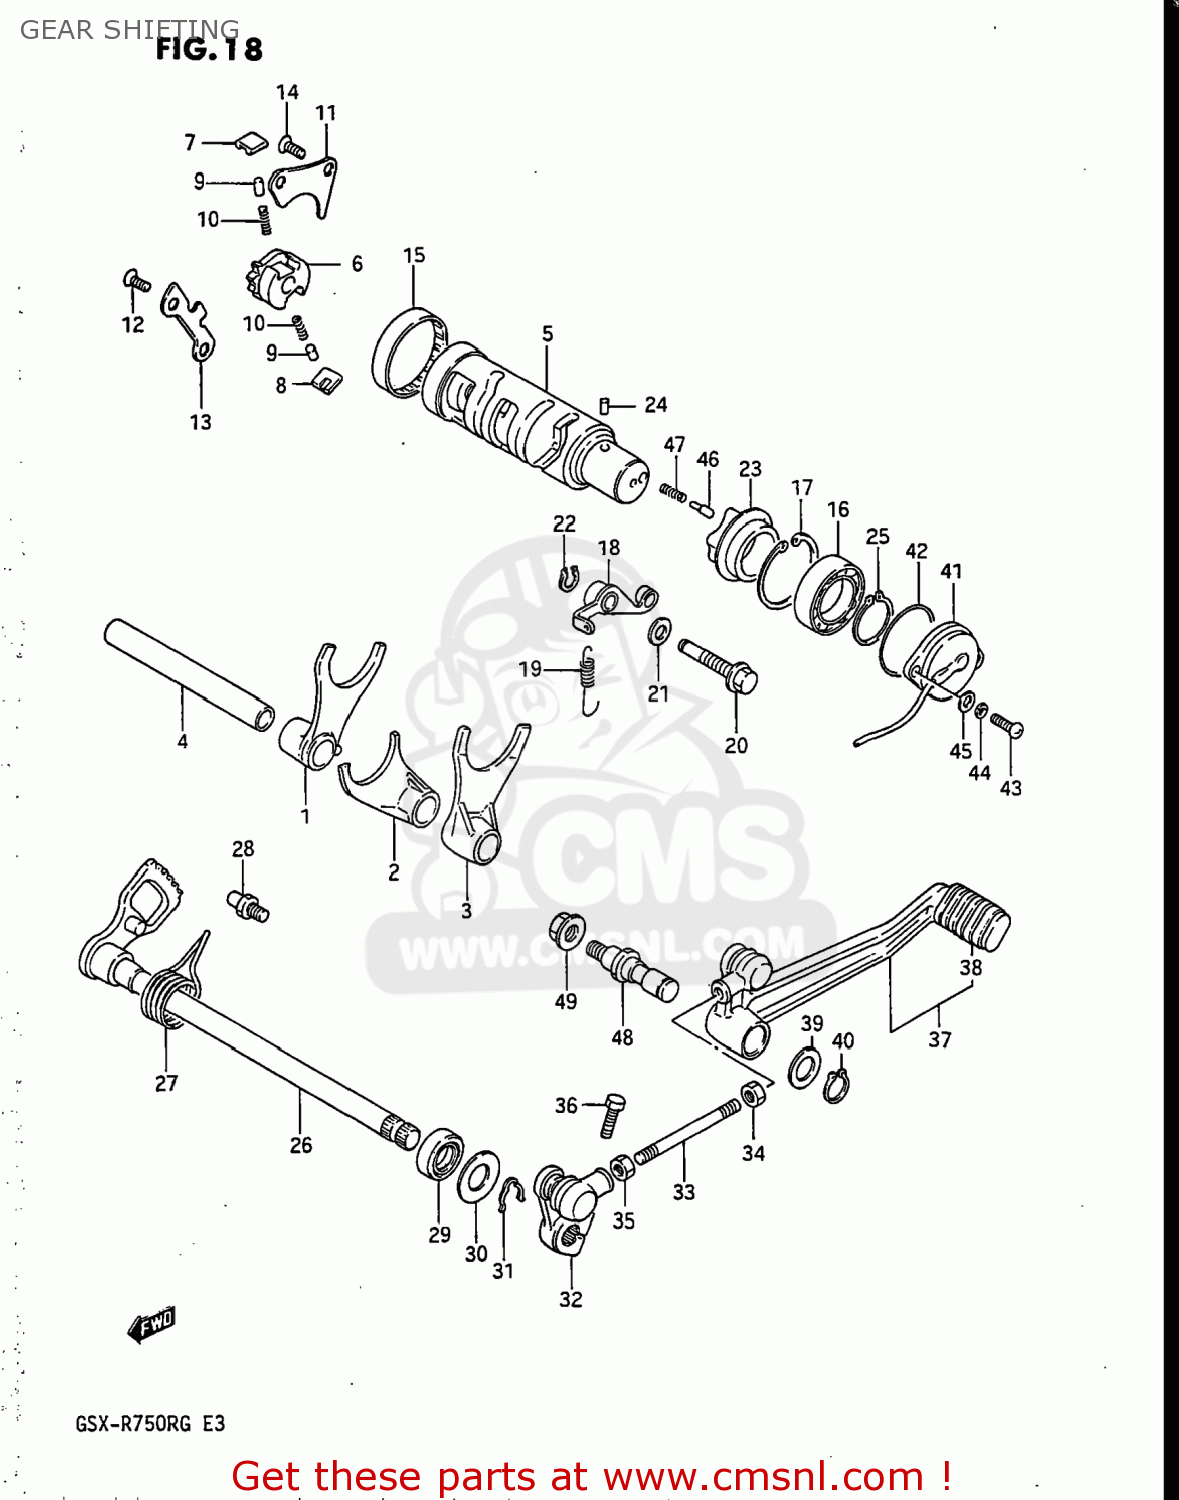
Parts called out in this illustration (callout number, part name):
1	FORK,GEAR SHIFT NO.1
2	FORK,GEAR SHIFT NO.2
3	FORK,GEAR SHIFT NO.3
4	SHAFT,GEAR SHIFT FORK(L:128)
5	CAM,GEAR SHIFT
6	GEAR,GEARSHIFT CAM DRIVE
7	PAWL,GEAR SHIFT NO.1
8	PAWL,GEAR SHIFT NO.2
9	PIN(5X8)
10	SPRING
11	LIFTER,GEAR SHIFT PAWL
12	SCREW
13	GUIDE,GEAR SHIFT CAM
14	SCREW
15	BEARING(43X49X12)
16	BALL BEARING
17	CIRCLIP,42MM
18	STOPPER,GEAR SHIFT CAM
19	SPRING
20	SHAFT,GEAR SHIFT CAM STOPPER
21	GASKET(10X14X3.6) (NAS)
22	CIRCLIP
23	PLATE,STOPPER
24	PIN 4X6
25	CIRCLIP,25MM
26	SHAFT,GEAR SHIFT
27	SPRING
28	STOPPER,GEAR SHIFT CAM
29	OIL SEAL
30	WASHER (12.5X27X1.6)
31	SPRING,RETAINER
32	ARM,GEAR SHIFT
33	ROD,GEAR SHIFT LINK
34	NUT
35	NUT 6MM
36	BOLT
37	LEVER ASSY,GEAR SHIFT
38	RUBBER,BRAKE PEDAL
39	WASHER(12.5X20X1)
40	CIRCLIP
41	TERMINAL BASE,NEUTRAL SWITCH
42	O RING(D:2.4,ID:36.5)
43	SCREW(5X14)
44	LOCK WASHER
45	WASHER
46	PIN(5X15.5)
47	SPRING
48	SHAFT,GEAR SHIFT LEVER
49	NUT
